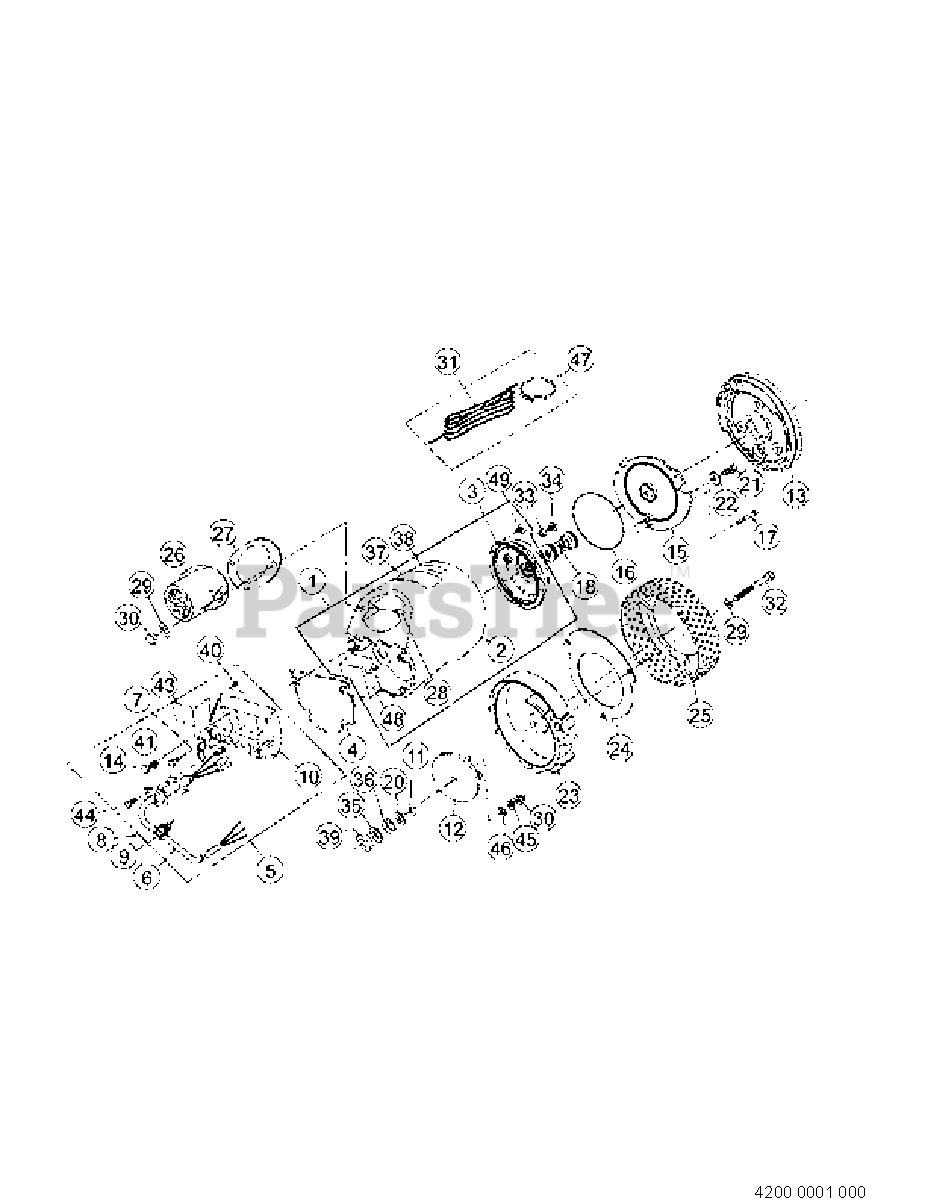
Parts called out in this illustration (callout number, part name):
2	FRAME
3	BRACKET
4	HEAD GASKET
6	POWER CORD
7	CHAIN AY
8	CORD SUPPORTER
9	CORD BAND
10	HANDLE
11	ADJUSTING WASHER
12	IMPELLER
13	BLACK LINER
14	HEX BOLT
15	FRONT COVER
16	O RING
17	HEX SOCKET BOLT
18	MECHANICAL SEAL
20	ADJUSTING WASHER
21	HEX SOCKET BOLT
22	SEAL WASHER
23	CASING
24	SUCTION FLANGE
25	STRAINER
26	DELIVERY FLANGE
27	DELIVERY FLANGE GASKET
28	STUD BOLT
29	WASHER
30	HEX CAP NUT
31	ROPE
32	HEX BOLT
33	SEAL RING
34	SCREW
35	THRUST WASHER
36	OIL SEAL
37	LABEL
38	CAUTION LABEL
39	THRUST GASKET
40	SCREW
41	SCREW
42	HEX NUT
43	LABEL
44	SCREW
45	TOOTHED WASHER
46	WASHER
47	HOSE BAND
49	HEX BOLT
